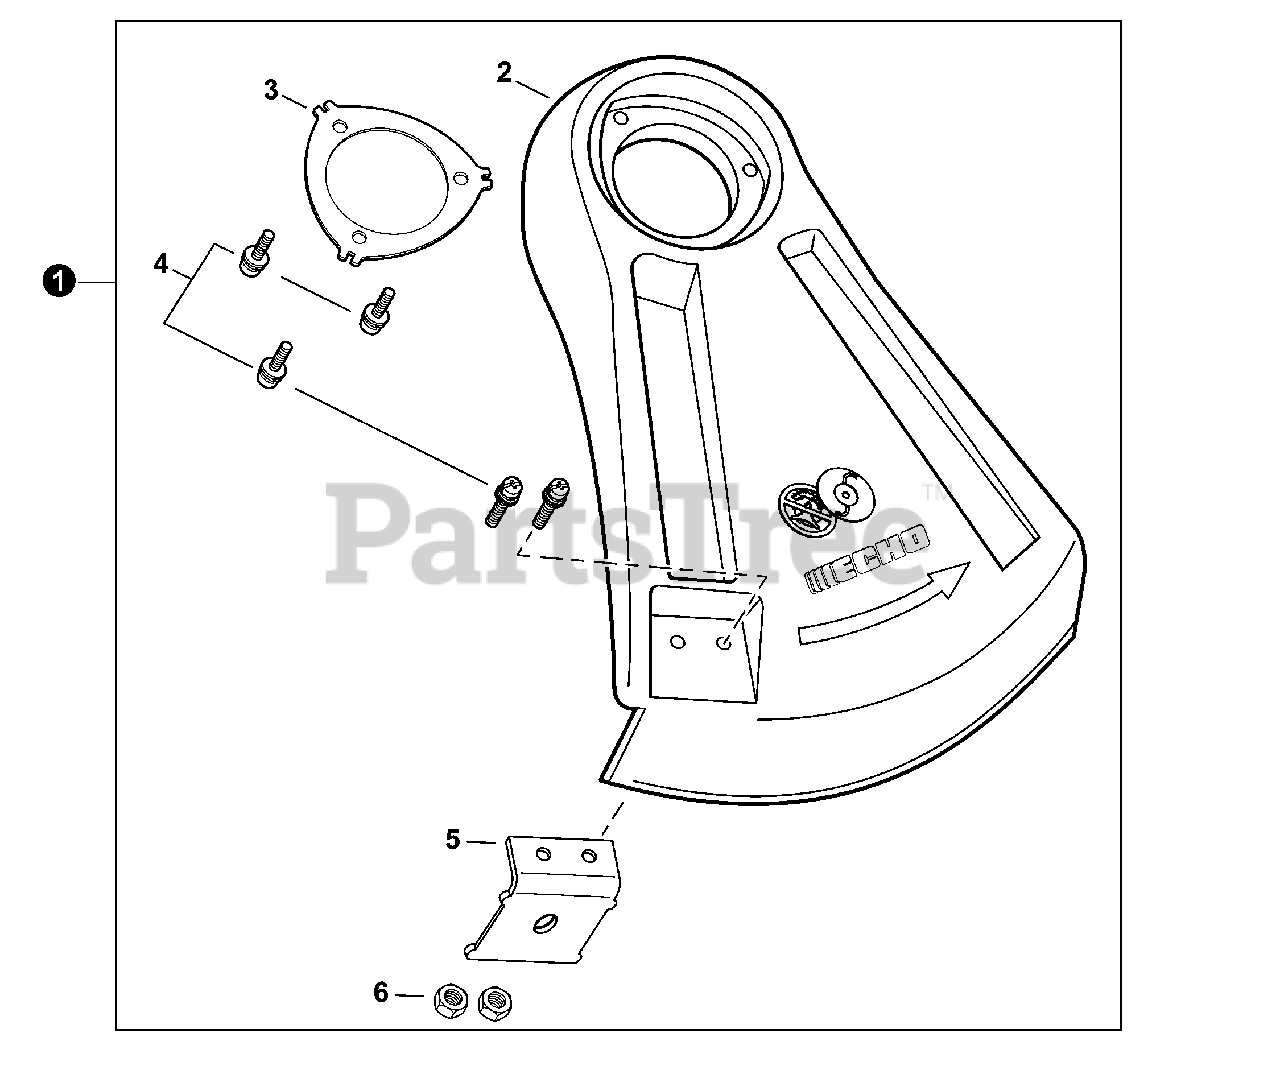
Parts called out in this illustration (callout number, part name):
1	DEBRIS SHIELD KIT
2	SHIELD, DEBRIS PLASTIC
3	PLATE, SHIELD
4	SCREW 5×16
5	CUTTER, LINE
6	NUT M5
